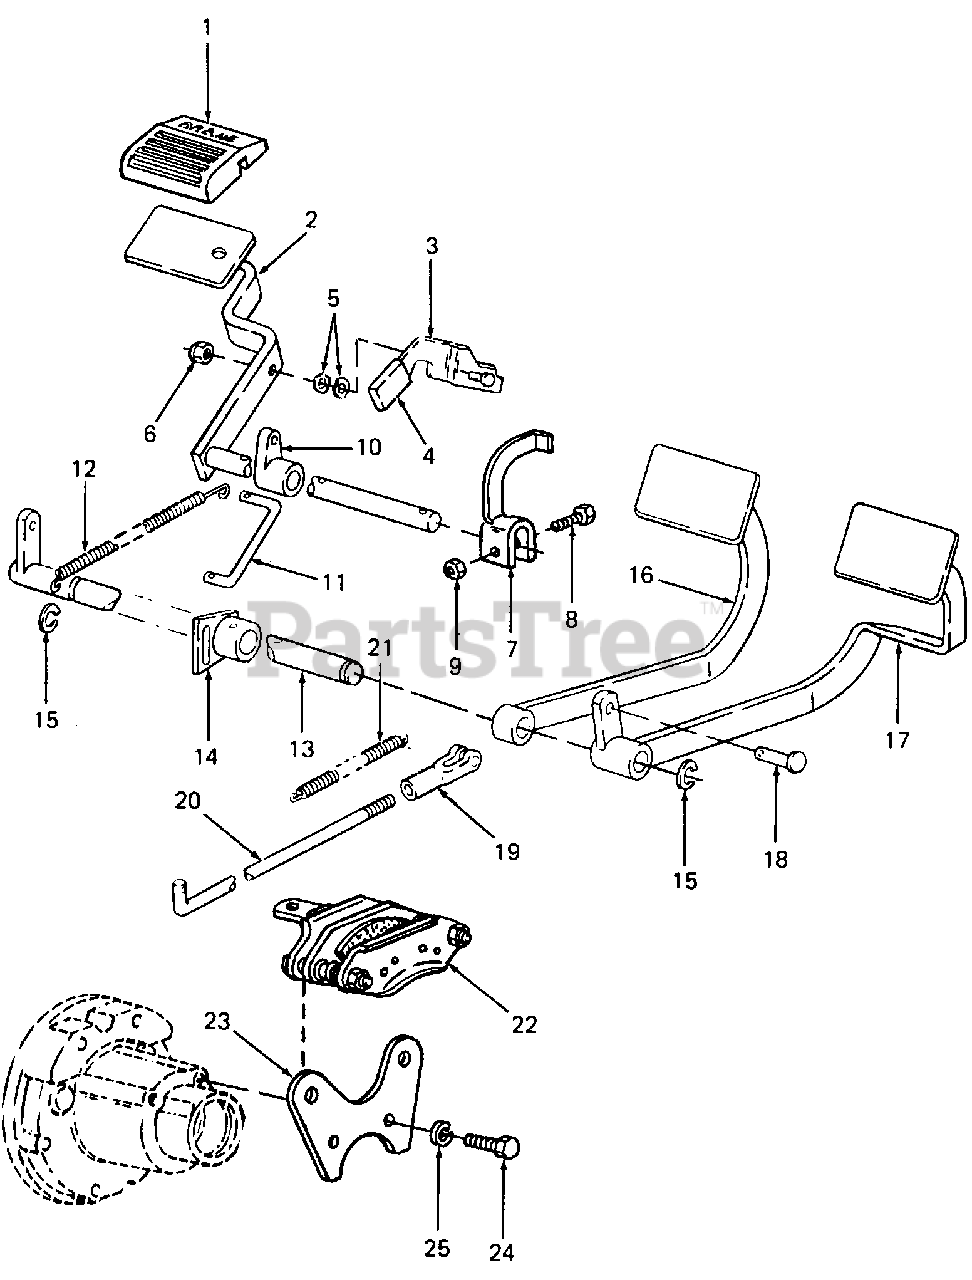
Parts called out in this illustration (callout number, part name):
1	Pad, Brake Pedal
5	Washer, Wave, 1/4 Dia
6	Nut, Hex Insert Lock, 1/4-20
9	Nut, Hex Center Lock, 1/4-20
11	Rod, Center Brake
12	Spring, Extension, .50 OD X 7.32 Lg
13	Shaft Assy, Brake
14	Arm Assy, Parking Brake Plate
15	Ring, Retaining
18	Pin, Clevis, 3/8 Dia X 1.56 Lg
19	Clevis, Adjustment
20	Rod, Brake
21	Spring, Extension, .66 OD X 3.3 Lg
22	Kit, Brake Caliper
23	Bracket, Brake Mounting
24	Screw, Hex Cap, 5/16-18 X 1.0 Lg GR5
25	Washer, Lock, 5/16
